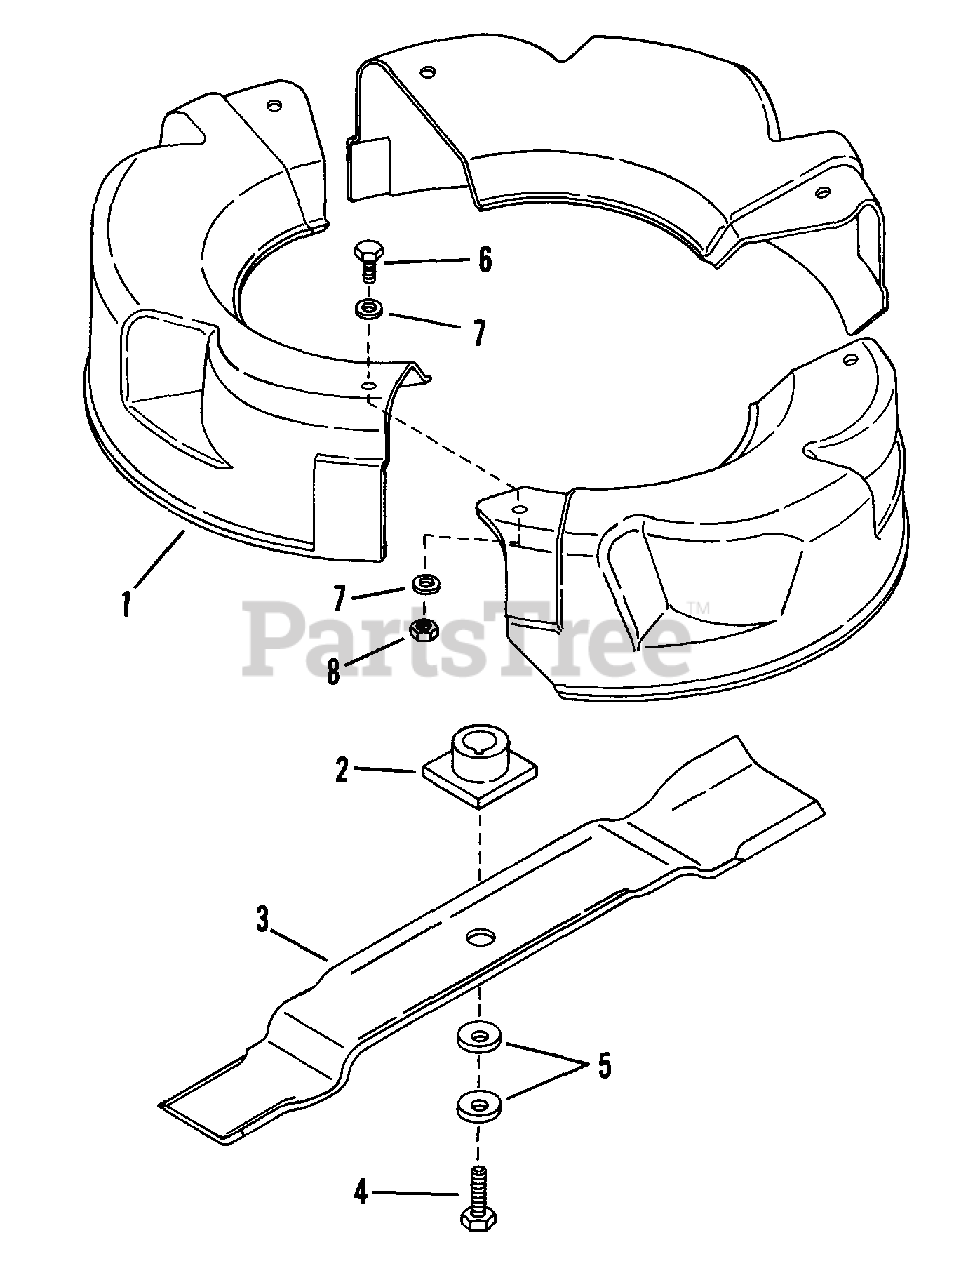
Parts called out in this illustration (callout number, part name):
2	HUB, 7/8" I.D.
3	BLADE, Mulcherizer
4	SCREW, 3/8-24 x 1-3/4" Hex Head Cap, Grade 5
5	WASHER, Cone
6	SCREW, 1/4-28 x 5/8" Hex Head Cap, Grade 5
7	WASHER, 1/4" Flat
8	NUT, 1/4-28 Hex Top Lock
